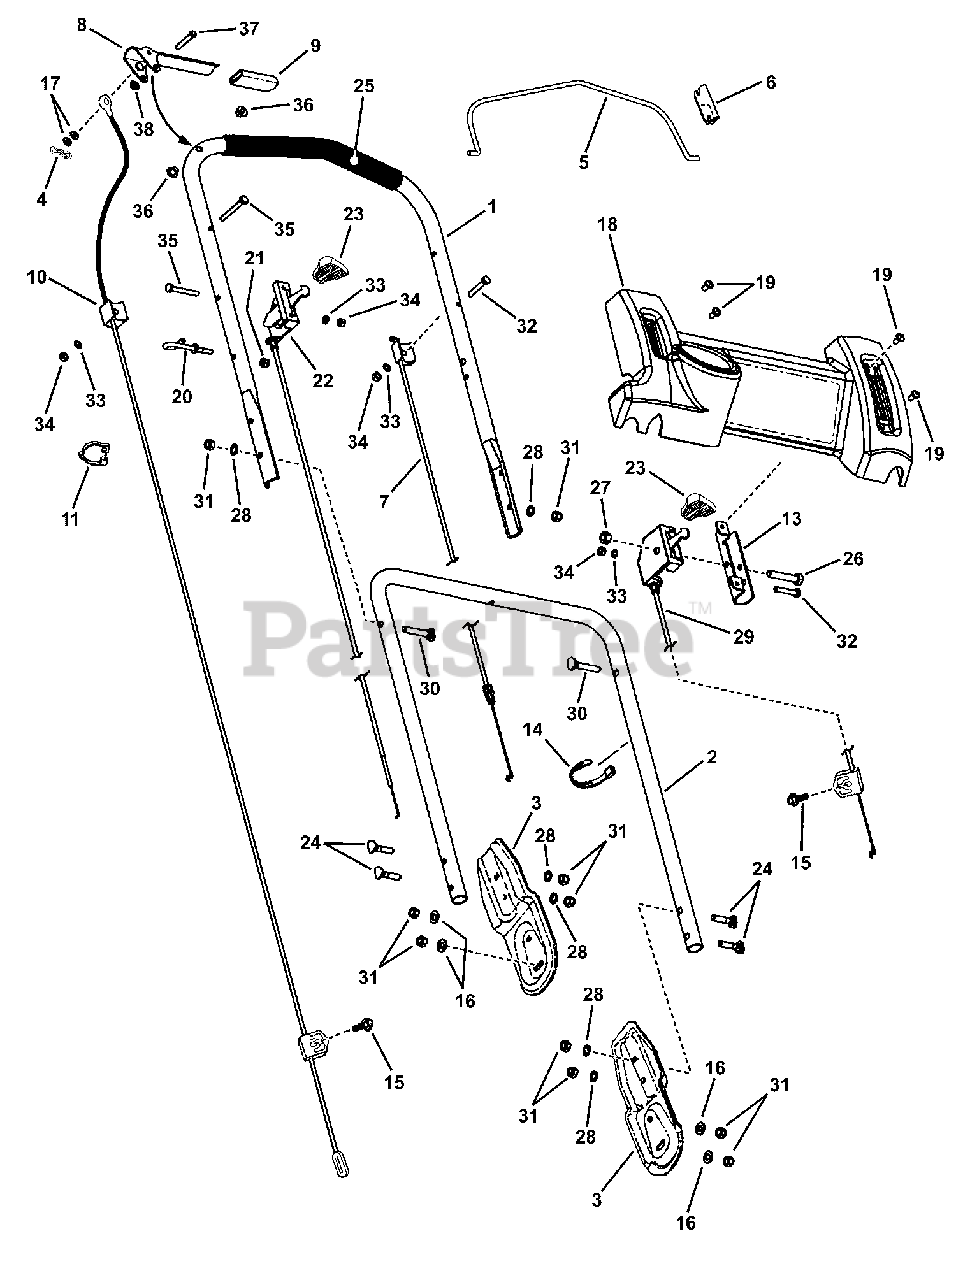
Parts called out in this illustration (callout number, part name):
1	HANDLE, Upper
2	HANDLE, Middle
3	BRACKET, Handle
4	COTTER PIN, Bow Tie Locking
5	BAIL, OPC Control
6	CLIP, Zone Control
7	CABLE, Zone Control
8	ASSEMBLY, Handle Clutch
9	GRIP, International Symbol
10	CABLE, Clutch (Adjustable)
11	CLAMP, 7/8" Double Cable
13	BRACKET, Shift
14	WIRE TIE, 1.29" Long Black
15	SCREW, #10-24 x 5/8" Slotted Hex Washer Head Self-Tap
16	WASHER, 11/32" Flat
17	WASHER, 7/32" Flat
18	CONTROL PANEL (w/o El. Switch Hole)
19	SCREW, 1/4-20 x 1/2" Pan Head Self-Tap (Torx)
20	ROPE GUIDE (1/4-20 threads)
21	NUT, 1/4-20 Hex Nyloc
22	THROTTLE CONTROL, 6.0 KWV (53.25" Long)
23	THROTTLE KNOB
24	BOLT, 5/16-18 x 1-1/2" Curved Head Carriage
25	FOAM GRIP, 18.75"
26	SCREW, 3/8-16 x 2" Hex Head Self-Tap
27	NUT, 3/8-16 Hex Center Lock
28	WASHER, 5/16" Internal Tooth Lock
29	CONTROL, Speed Select
30	SCREW, 5/16-18 x 2" Square Neck Curved Head
31	NUT, 5/16-18 Hex Nyloc
32	SCREW, 1/4-20 x 1-1/2" Hex Head Cap GR 5
33	WASHER, 1/4" Internal Tooth Lock
34	NUT, 1/4-20 Hex
35	SCREW, 1/4-20 x 2" Hex Head Cap GR 5
36	BUSHING, .27 x .35 x .4 Flange
37	PIN, 1/4 x 1-1/2"
38	PUSHNUT, 1/4"
